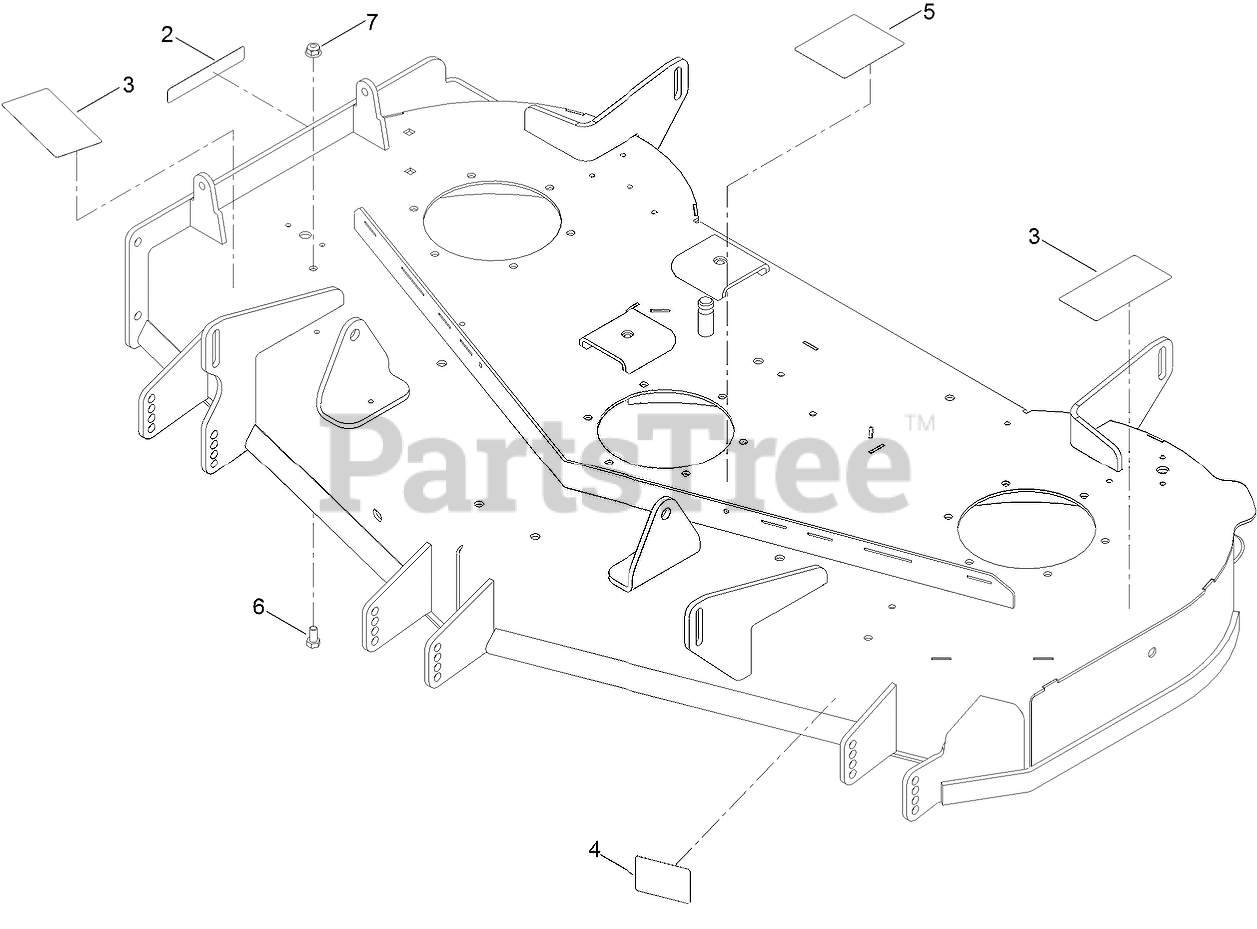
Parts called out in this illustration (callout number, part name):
2	DECAL-DANGER
3	DECAL-DANGER, DECK
4	DECAL-SCALP, ANTI
5	DECAL-ROUTING, BELT
6	SCREW-HH
7	NUT-HF, NI
